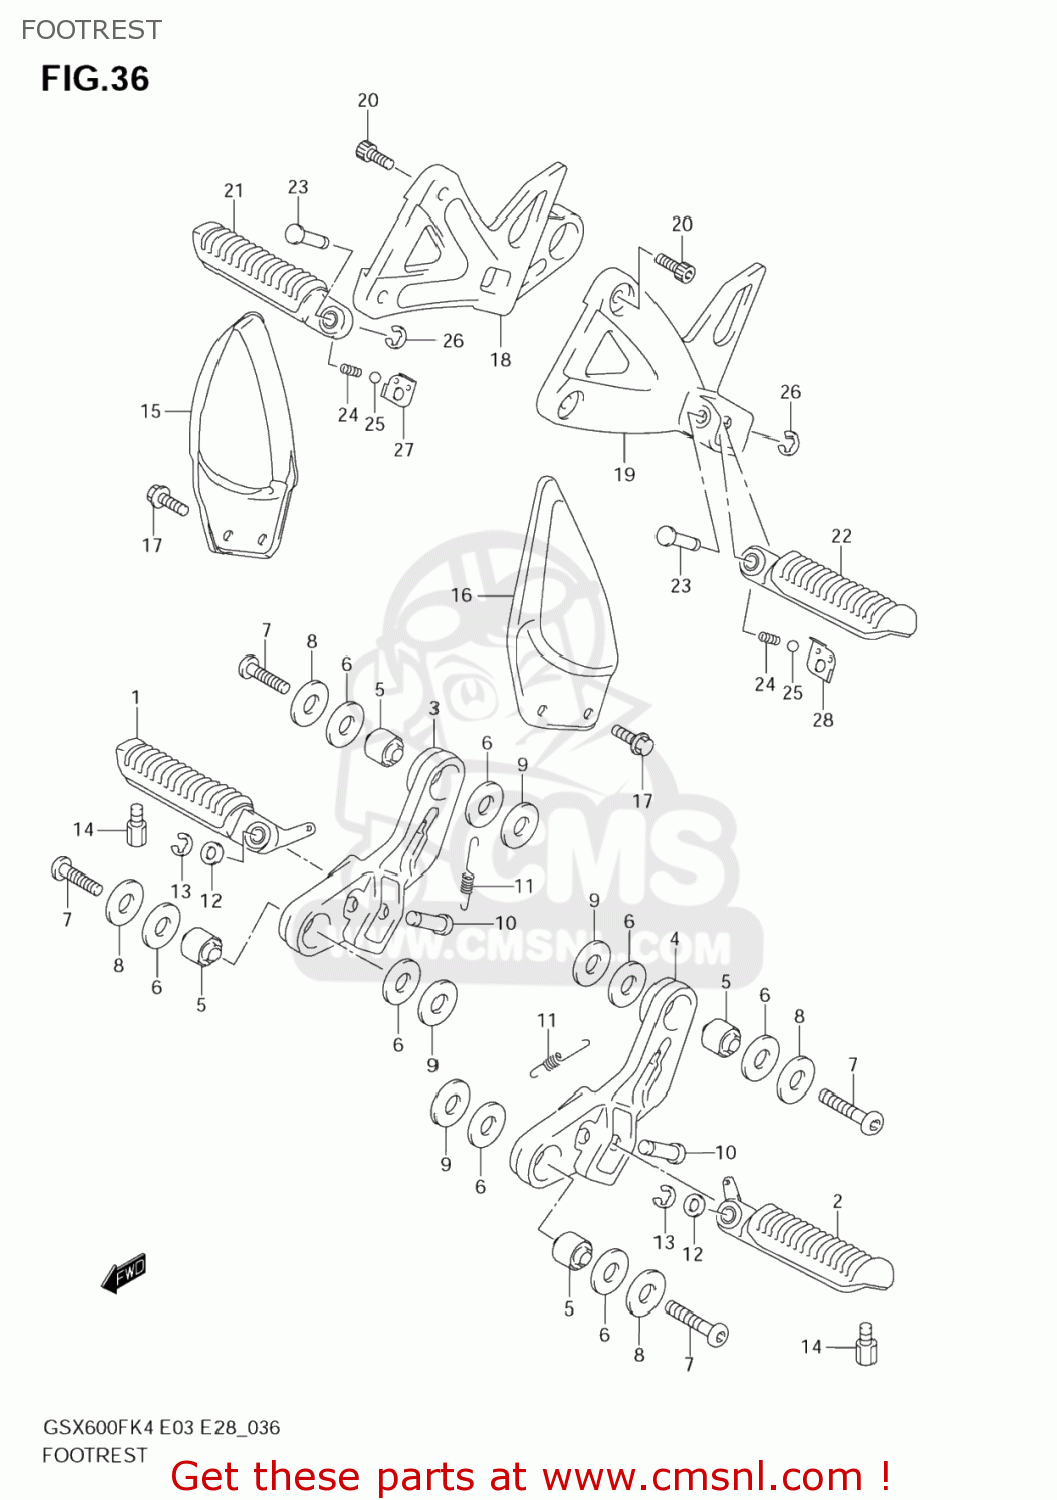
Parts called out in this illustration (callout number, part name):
1	BAR,FRONT FOOTREST,RIGHT
2	BAR,FRONT FOOTREST,LEFT
3	HOLDER,FR FOOTREST,R
4	HOLDER,FR FOOTREST,L
5	BUSH(8.4X20X18)
6	WASHER(12.5X30X2)
7	BOLT(8X33)
8	WASHER (8.5X30X2.3)
9	WASHER(8.5X30X2.3)
10	PIN(8X33.2)
11	SPRING
12	WASHER
13	E.RING
14	BOLT,BANK SENSOR
15	GUARD,FR FOOTREST,R
16	GUARD,FR FOOTREST,L
17	BOLT(8X16)
18	BRACKET,PILLION FOOTREST,R
19	BRACKET,PILLION FOOTREST,L
20	BOLT(8X23)
21	BAR,PILLION FOOTREST,R
22	BAR,PILLION FOOTREST,L
23	PIN
24	SPRING
25	BALL
26	E.RING
27	PLATE,PILLION FOOTREST,R
28	PLATE,PILLION FOOTREST,L
